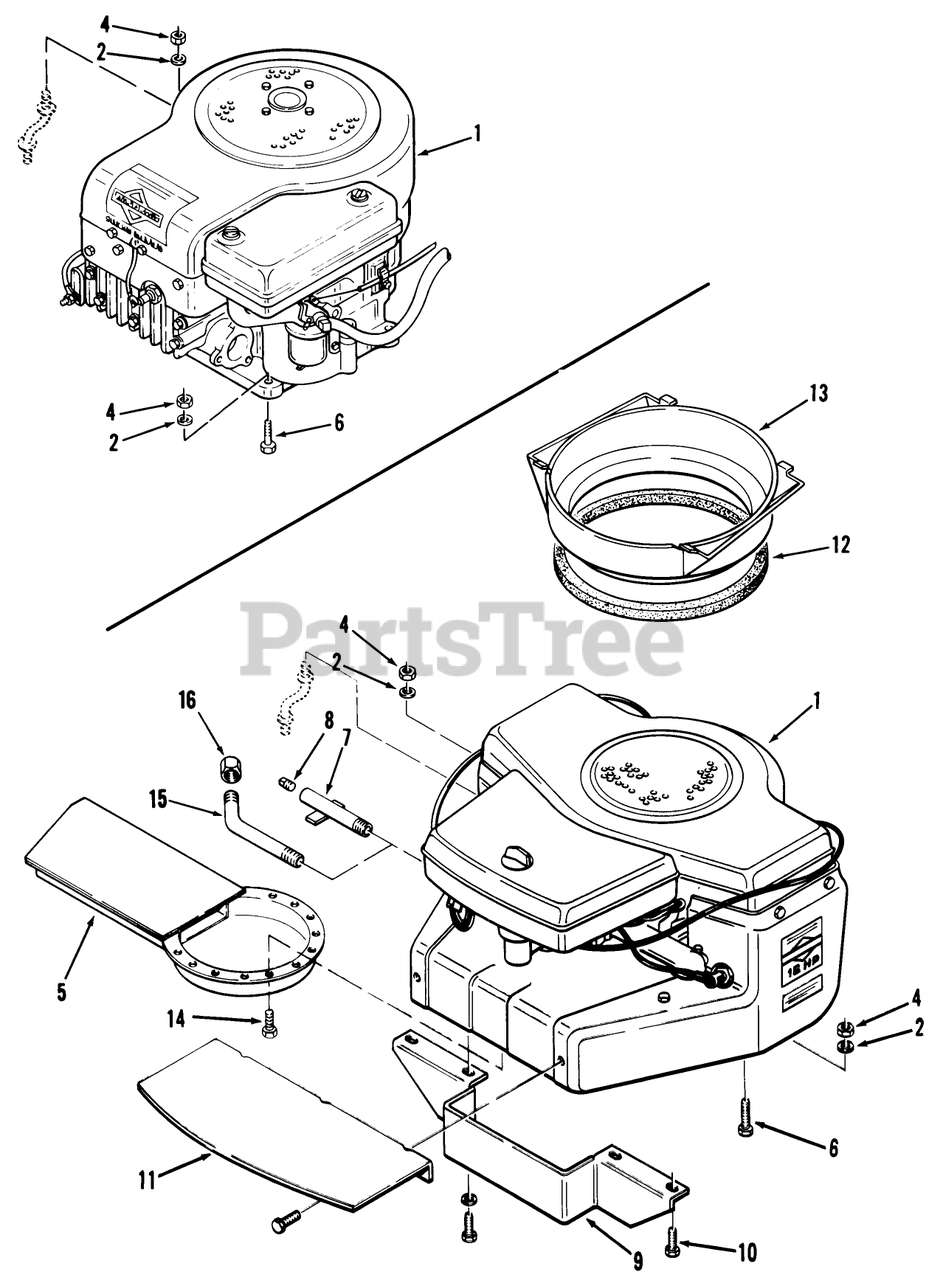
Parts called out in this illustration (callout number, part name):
1	Engine-11HP-BS Model 252707, Type 0209-01
1	Engine-16HP-BS Model 401707, Type 0632-01 Later Production
1	Engine-16HP-BS Model 402707, Type 0130-03, LT-1637 Only
1	Engine-8HP-BS Model 191707, Type 1136-02-B-85 Only
2	WASHER 5/16 SAE
13	DUCT-AIR INTAKE
